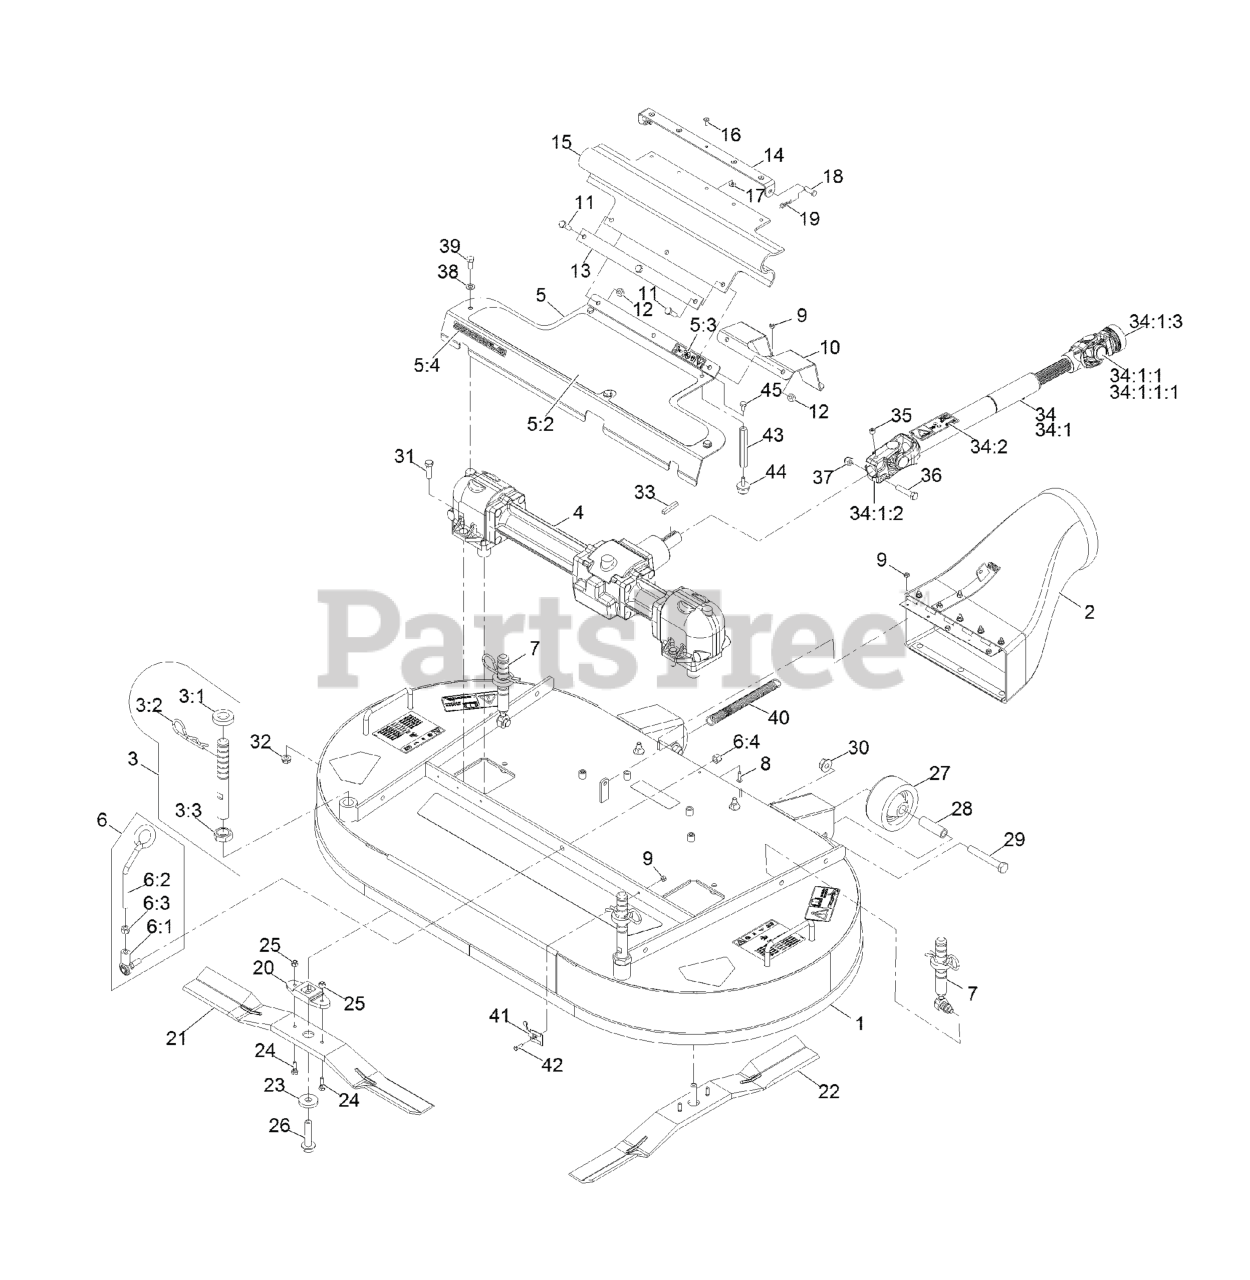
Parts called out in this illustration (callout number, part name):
1	DECK DECAL AND BAFFLE ASM
2	DISCHARGE TUBE ASM
3	FRONT DECK HEIGHT ADJUST
3:1	SPACER-DECK SUPPORT
3:2	PIN-CUT HEIGHT
3:3	NUT-JAM
4	GEAR BOX ASM
5	ASM,GEARBOX COVER 48 W/DE
5:2	PAD-ANTI SKID
5:3	DECAL-DANGER
5:4	Decal-Commercial 48
6	DECK LATCH ASM
6:1	BALLJOINT-RH
6:2	LATCH-DECK
6:3	NUT-HEX
6:4	NUT-LOCK
7	REAR DECK HEIGHT ADJUST A
8	SCREW-HEAD, TRUSS
9	NUT-LOCK, NI
10	GUARD-DRIVE SHAFT
11	SCREW-HH
12	NUT-LOCK, NI
13	STRAP-DRIVE, LINE COVER
14	BRACKET-GUARD, PTO
15	GUARD-PTO
16	RIVET-BLIND
17	WASHER-FLAT
18	PIN-CLEVIS
19	PIN-COTTER
20	DRIVER-BLADE
21	BLADE,25 INCH RH
22	BLADE,25 INCH LH
24	BOLT-SHEAR
25	NUT-LOCK, NI
26	BOLT-BLADE
27	ROLLER-DECK
28	SPACER-ROLLER
29	SCREW-HH
30	NUT-HHF
31	SCREW-HH
32	NUT-HHF, WHIZ
33	KEY-SQUARE
34	DRIVE SHAFT ASM
34:1	Drive Shaft-Telescoping
34:1:1	U-JOINT KIT
34:1:1:1	FITTING-GREASE
34:1:2	YOKE-KEYED
34:1:3	YOKE-QUICK DISCONNECT
34:2	DECAL-DANGER, DRIVELINE
35	SCREW-SET, HSH
36	SCREW-HH
37	NUT-LOCK, NI
38	WASHER-PLAIN
39	SCREW-HH
40	SPRING-EXTENSION
41	CLIP-DECK, HOLD UP ROD
43	STAND-OFF
45	SCREW-HH
